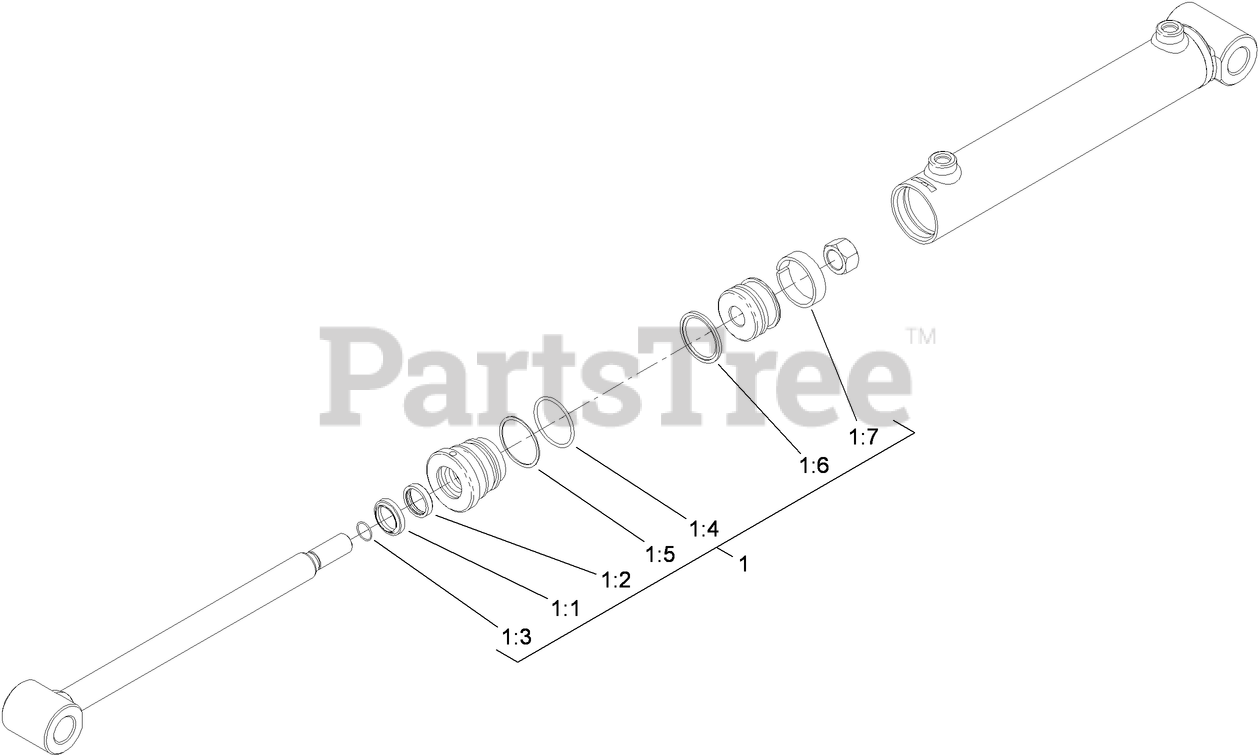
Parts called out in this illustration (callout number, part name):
1	SEAL KIT
1:1	WIPER
1:2	U-CUP
1:3	O-RING
1:4	O-RING
1:5	BACK-UP RING
1:6	CAPSEAL
1:7	WEAR RING
